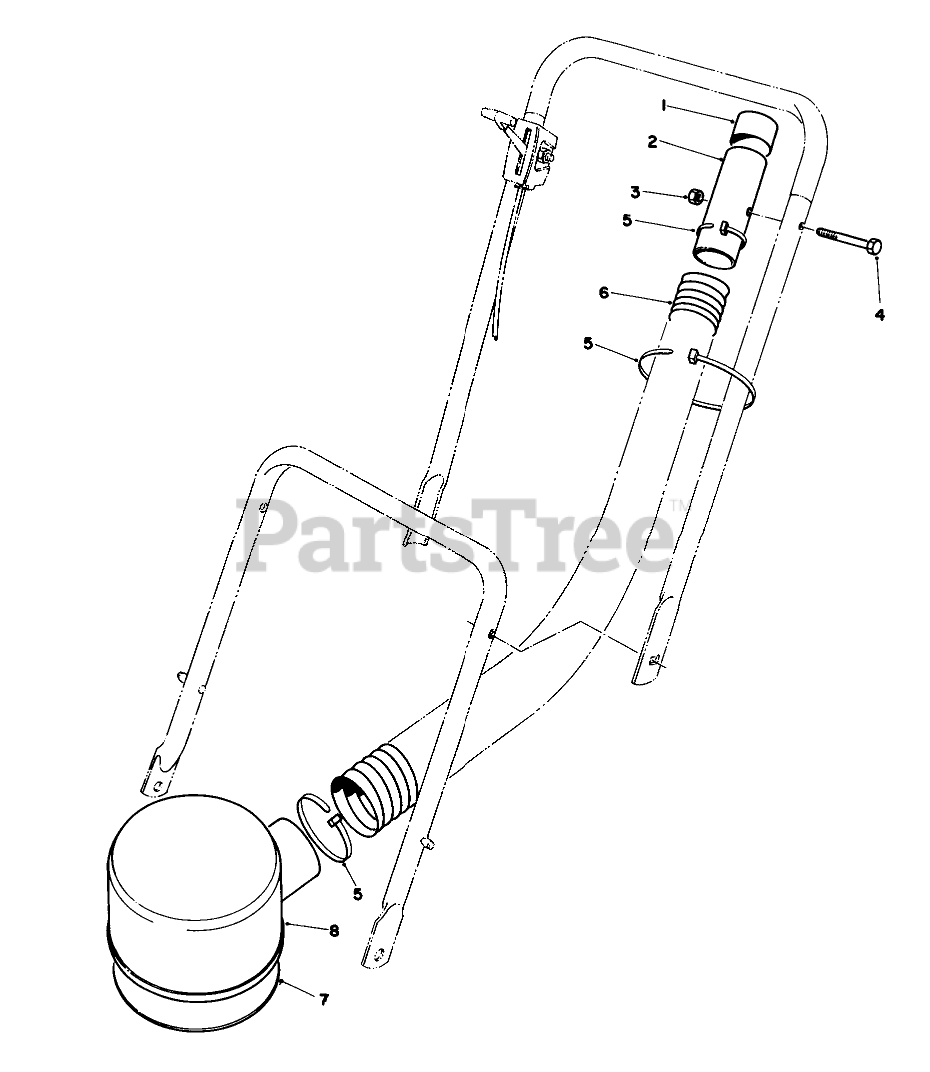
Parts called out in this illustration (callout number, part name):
1	BLACK CAPLUG
2	AIR CLNR HOSE TIP
3	NUT-LOCK, CONE
4	SCREW-HH
5	TIE-CABLE
6	AIR CLEANER HOSE
7	AIR CLEANER BASE
8	Air Cleaner Cover
